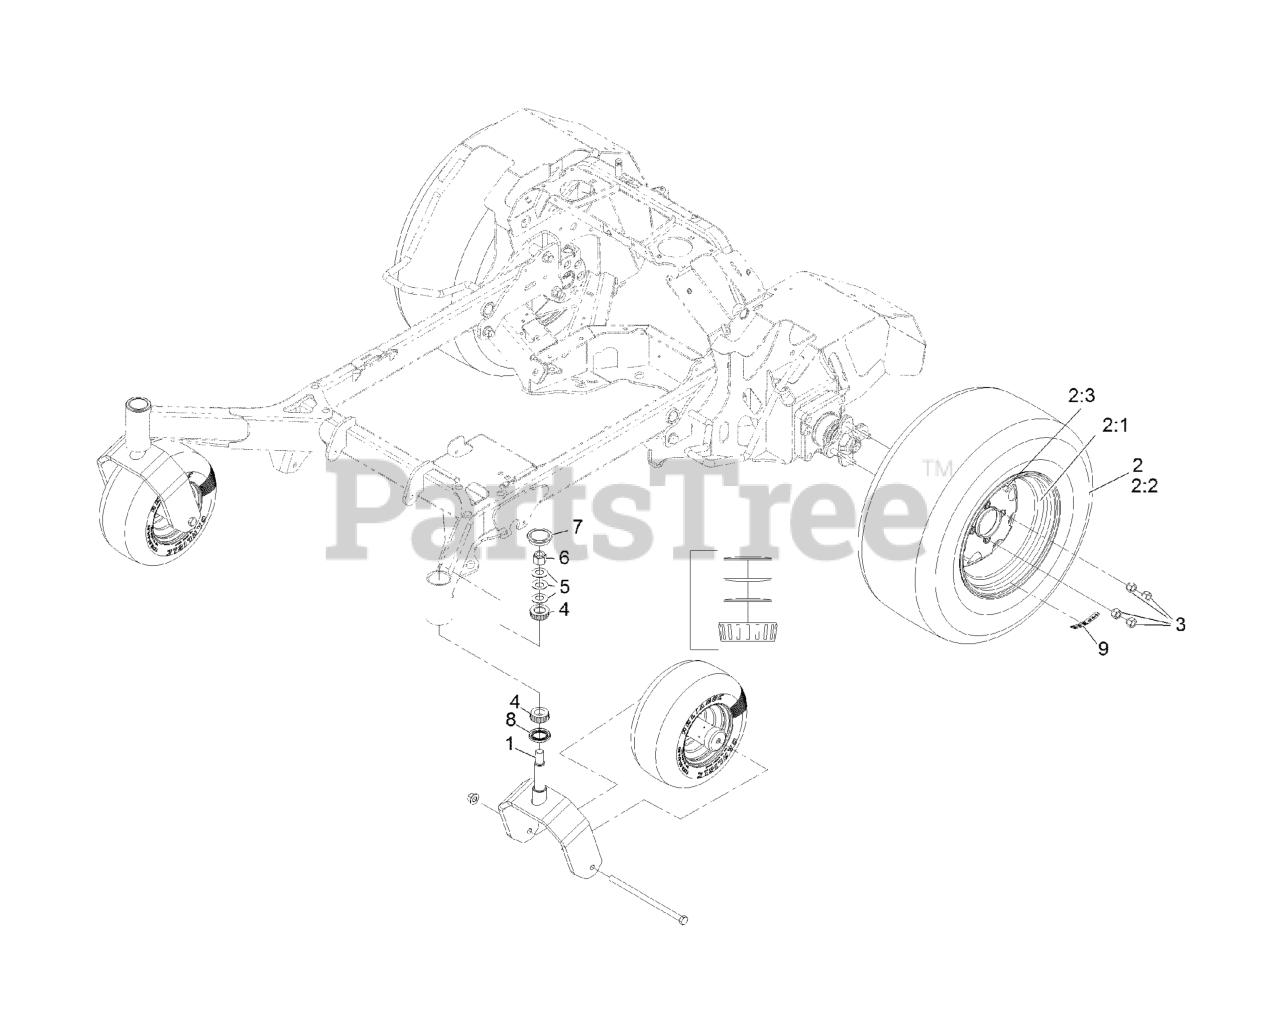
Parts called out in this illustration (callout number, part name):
2	ASM, WHEEL AND TIRE
2:1	RIM, 12 X 8.5
2:3	Stem-Valve
3	NUT-LUG
4	Cone-Bearing Tapered Roller
5	WASHER-BELLVILLE
6	NUT-LOCK, NI
7	CAP-GREASE
8	SEAL-GREASE
9	DECAL-TORQUE, WHEEL HUB LUG
